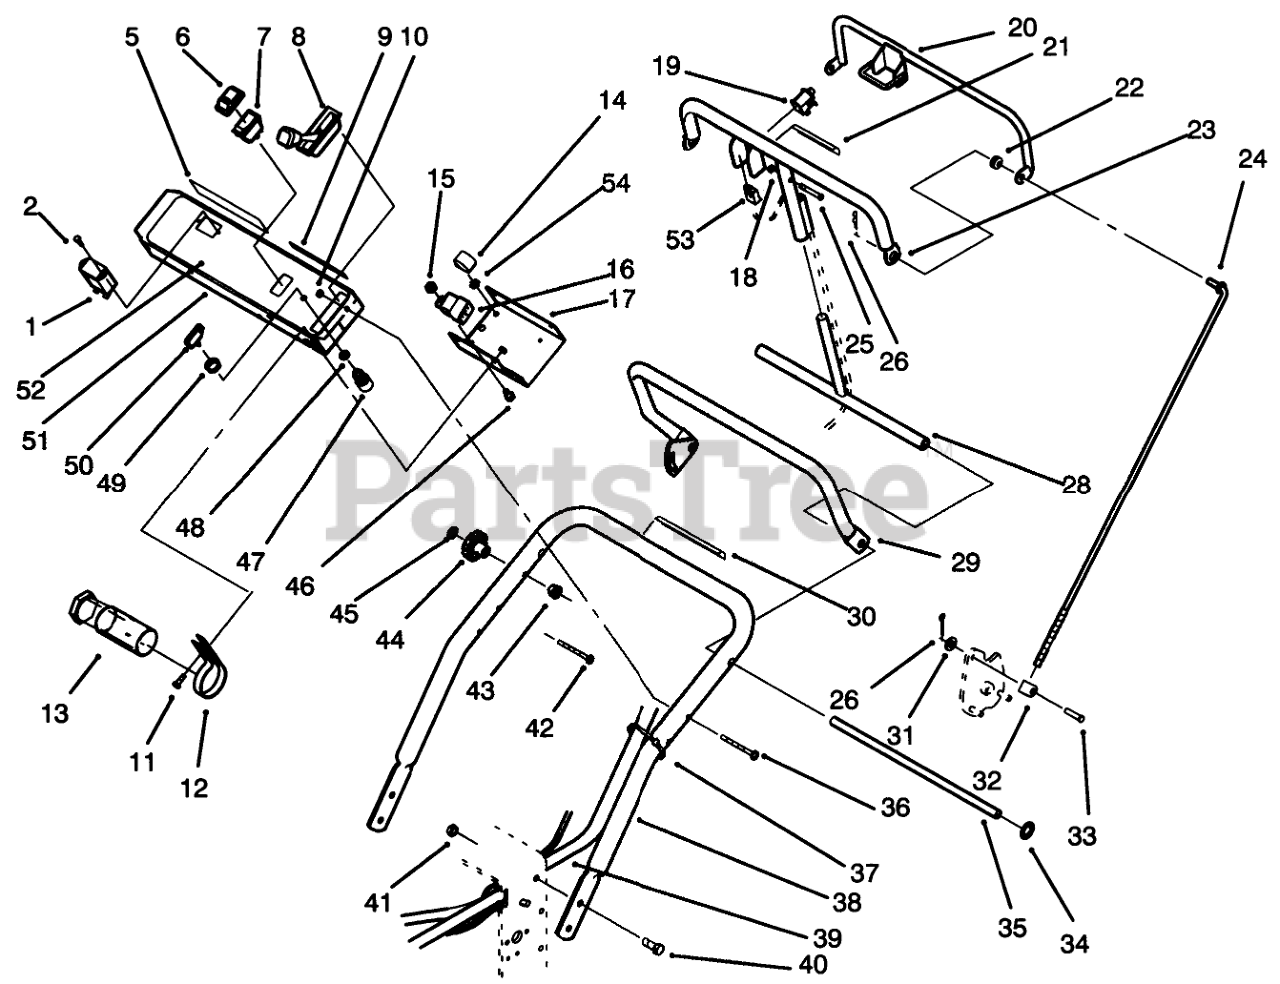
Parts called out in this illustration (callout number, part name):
1	HOURMETER
2	SCREW-HWH
3	SPACER
4	CHOKE CONTROL
5	DECAL-INSTRUCTION, SAFETY
6	BOOT-SWITCH
7	SWITCH
8	THROTTLE CONTROL
9	DECAL-INSTRUCTION
10	NUT-LOCK, NI
11	SCREW-SHWH
12	CLAMP-R
13	TUBE-MANUAL
14	Module
15	NUT-LOCK, NI
16	RELAY
17	Panel-Bottom
18	NUT-LOCK, NI
19	SWITCH-BAIL
20	Bail
21	DECAL - CONTROL BAR
22	GROMMET-RUBBER
23	Bar
24	ROD-CONTROL
25	SCREW-SHH
26	PIN-COTTER
28	Pivot Control Assembly
29	REFERENCE HANDLE WA B
30	DECAL-WARNING
31	WASHER-PLAIN
32	FITTING-ROD
33	PIN-CLEVIS
34	NUT-PUSH-ON, CIRCULAR
35	PIVOT ROD
36	SCREW-SHH
37	TIE-CABLE
38	UPPER HANDLE R
39	WIRE HARNESS
40	SCREW-HHF
41	NUT-HF
42	SCREW-CARR
43	SPACER
45	BOLT RETAINER
46	SCREW-HH
47	SWITCH-STARTER
48	SCREW-HHF
49	NUT-HH
50	KEY-IGNITION
51	Panel-Control
52	DECAL - CONTROL PANEL
53	CONNECTOR-BODY
54	WASHER-LOCK/EXT
